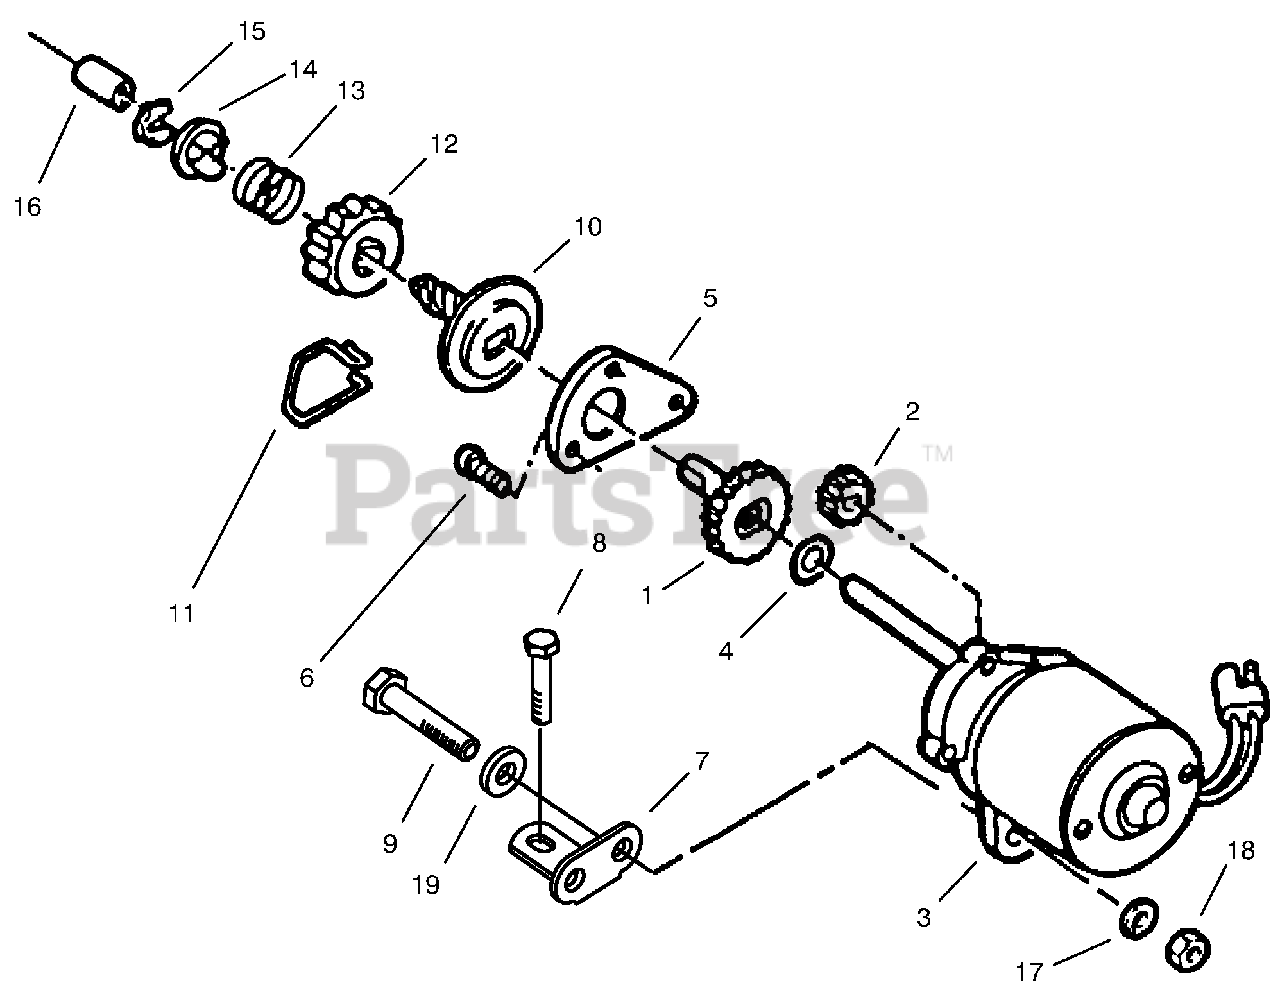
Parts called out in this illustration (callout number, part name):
1	Gear-Driven
2	Pinion-Motor shaft
3	Motor Housing & Pin Ass'y
4	Washer
5	Plate-Gear Cover
7	Bracket-Starter Mounting
10	Pinion-Spring & Clutch Ass'y (Incl. Ref. #11-15)
11	Spring-Drag
13	Spring-Pinion Return
14	Washer-Pinion Stop
15	Ring-Retaining
17	Washer-Lock
18	Nut
19	Washer
